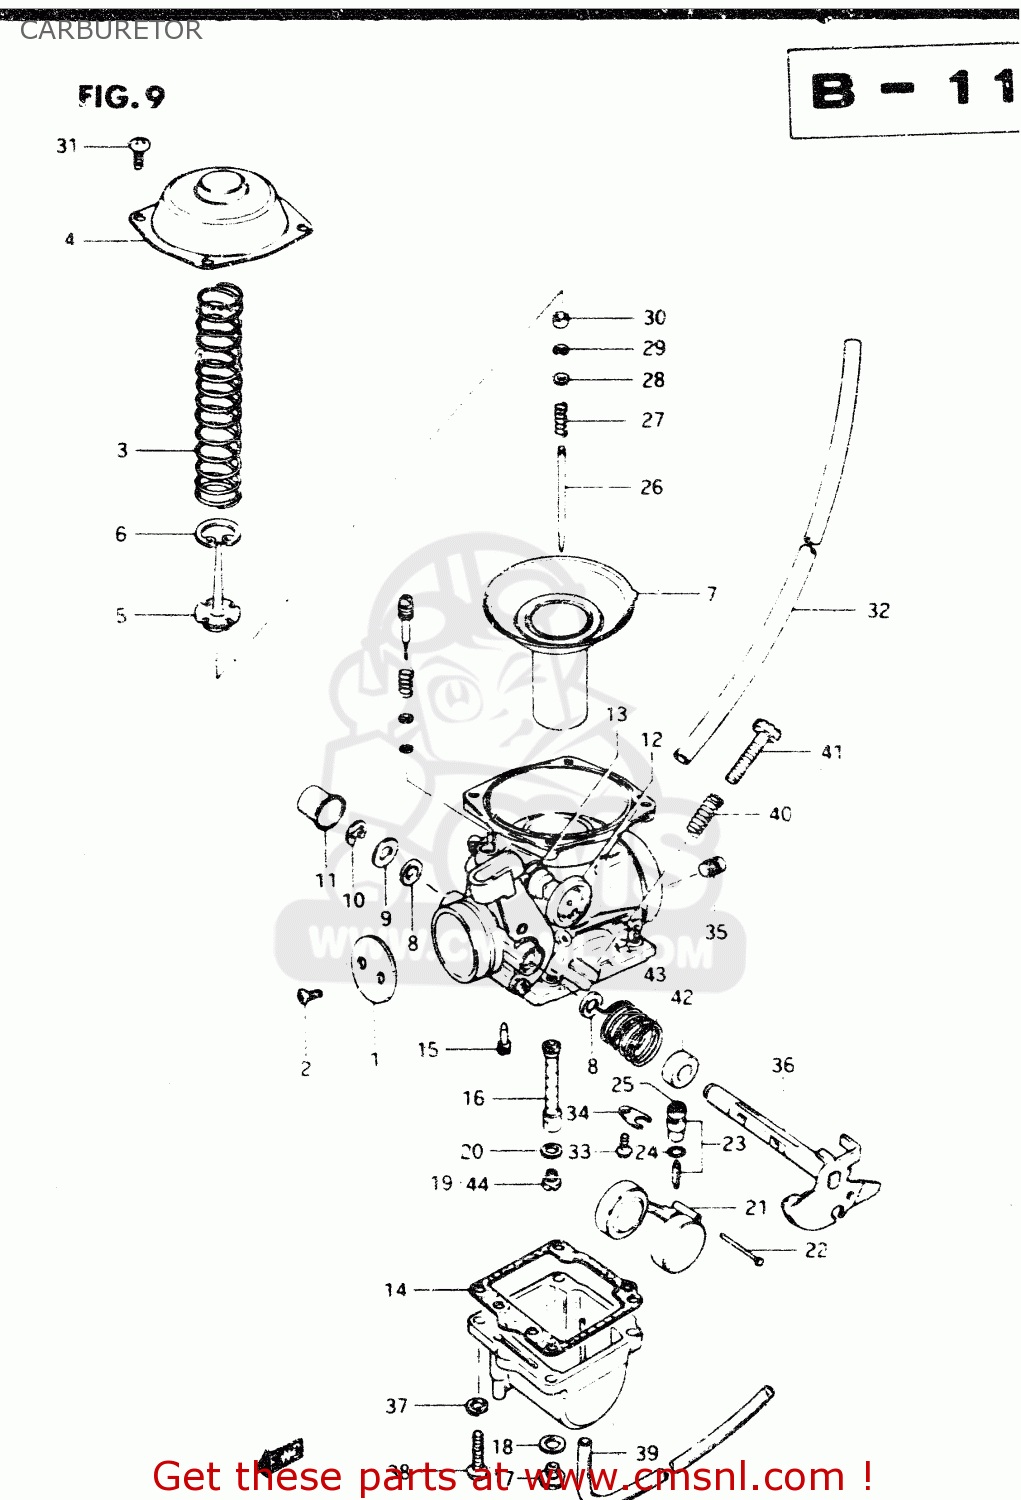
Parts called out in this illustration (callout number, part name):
1	THROTTLE VALVE (100)
2	SCREW
3	SPRING
4	COVER
5	HOLDER,GUIDE
6	E RING
7	DIAPHRAGM ASSY
8	SEAL
9	GASKET,THROTTLE SHAFT (NAS)
10	E RING
11	CAP
12	STARTER VALVE
13	O RING
14	GASKET,FLOAT CHAMBER (NAS)
15	JET,PILOT(42.5)
16	JET, NEEDLE (P-1)
17	PLUG,DRAIN
18	GASKET (NAS)
19	JET,MAIN(125)
20	WASHER
21	FLOAT
22	PIN,FLOAT
23	VALVE ASSEMBLY,NEEDLE
24	O RING
25	FILTER
26	NEEDLE,JET
27	SPRING
28	WASHER
29	CLIP
30	RING
31	SCREW
32	HOSE
33	SCREW 4X6
34	PLATE
35	JET,AIR(140)
36	SHAFT ASSEMBLY,THROTTLE
37	LOCK WASHER
38	SCREW
39	HOSE
40	SPRING,THROTTLE ADJUST
41	SCREW,THROTTLE STOP
42	RING
43	SPRING,THROTTLE SHAFT
44	JET
